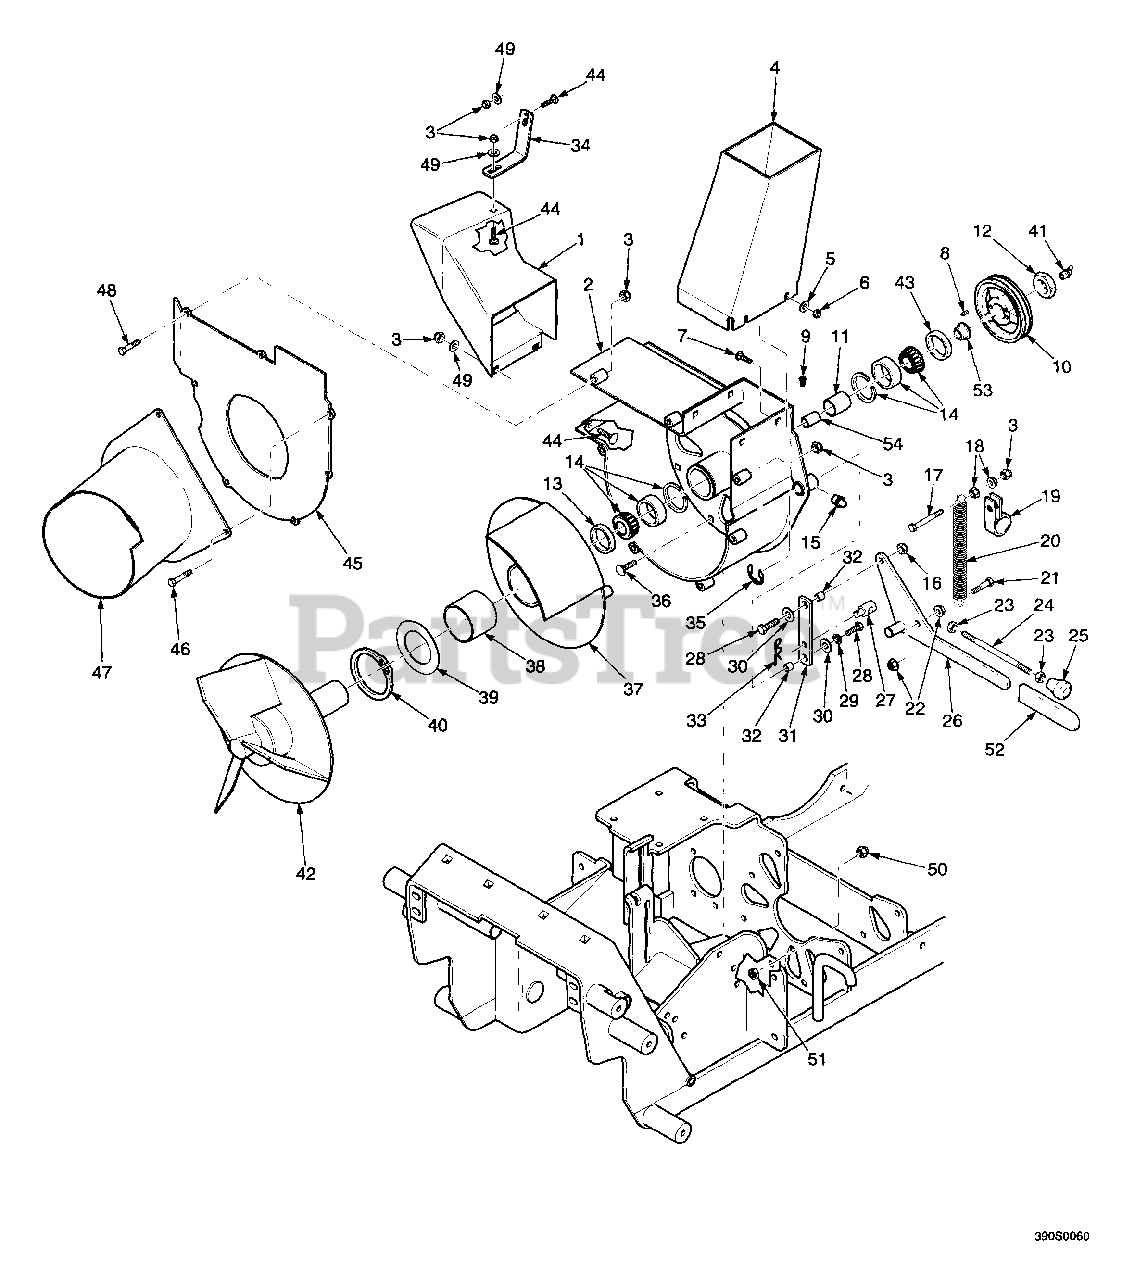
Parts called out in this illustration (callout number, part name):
1	Chute, Side Discharge
2	Housing, Blower
3	Hex Locknut, Elastic Stop, 5/16-18
4	Outlet, Blower
5	Flatwasher, 1/4 (.281 x .625 .065)
6	Hex Locknut, Elastic Stop, 1/4-20
7	Carriage Bolt, 1/4-20 x 3/4"
8	Key, 1/4 x .875 Woodruff
9	Relief Fitting
10	Pulley, 5.25 OD
11	Spacer, Outside
12	Nut, 1-1/16-18 L.H.
13	Seal, 2.00 OD x 1.50 Bore
14	Roller Bearing Assembly
15	Grease Fitting
16	Hex Locknut, 3/8-16
17	Bolt, Hex Head, 5/16-18 x 2-1/2"
18	Serr. Fl. Hex Nut, 5/16-18
20	Spring
21	Bolt, Hex Head, 3/8-16 x 1-1/2"
22	Serr. Fl. Hex Nut, 3/8-16
23	Hex Nut, 3/8-16
24	Stud, 3/8-16 x 9.00"
25	Knob, Shifter
26	Lever, Blower Gate
27	Joint, Swivel
28	Bolt, Hex Head, 3/8-16 x 1.0"
29	Lockwasher, 3/8"
30	Flatwasher, 3/8 (.406 x .812 x .065)
31	Link, Blower Gate
32	Sleeve
33	Hairpin, Cotter, .080 x 1.19"
34	Mounting Bracket, Discharge Chute
35	Retaining Ring, .625 "E"
36	Carriage Bolt, 3/8-16 x 1-1/4"
37	Gate
38	Bushing, Oilite, 2.505 ID
39	Washer, Gate Retainer
40	Retaining ring, 2.50 Ext
41	Grease Fitting 65ø
42	Fan, Blower
43	Seal, 2.00 OD x 1.625 Bore
44	Carriage Bolt, 5/16-18 x 3/4"
45	Front, Blower Housing
46	Bolt, Hex Head, 5/16-18 x 1-1/2"
47	Adapter, Blower Inlet
48	Bolt, Hex Head, 5/16-18 x 1-1/2"
49	Flatwasher, 5/16 (.375 x .875 x .083)
50	Hex Locknut, Elastic Stop, 3/8-16
51	Nut, Jam, 3/8-16
53	Spindle Bushing, Bottom
54	Spacer, Inside
